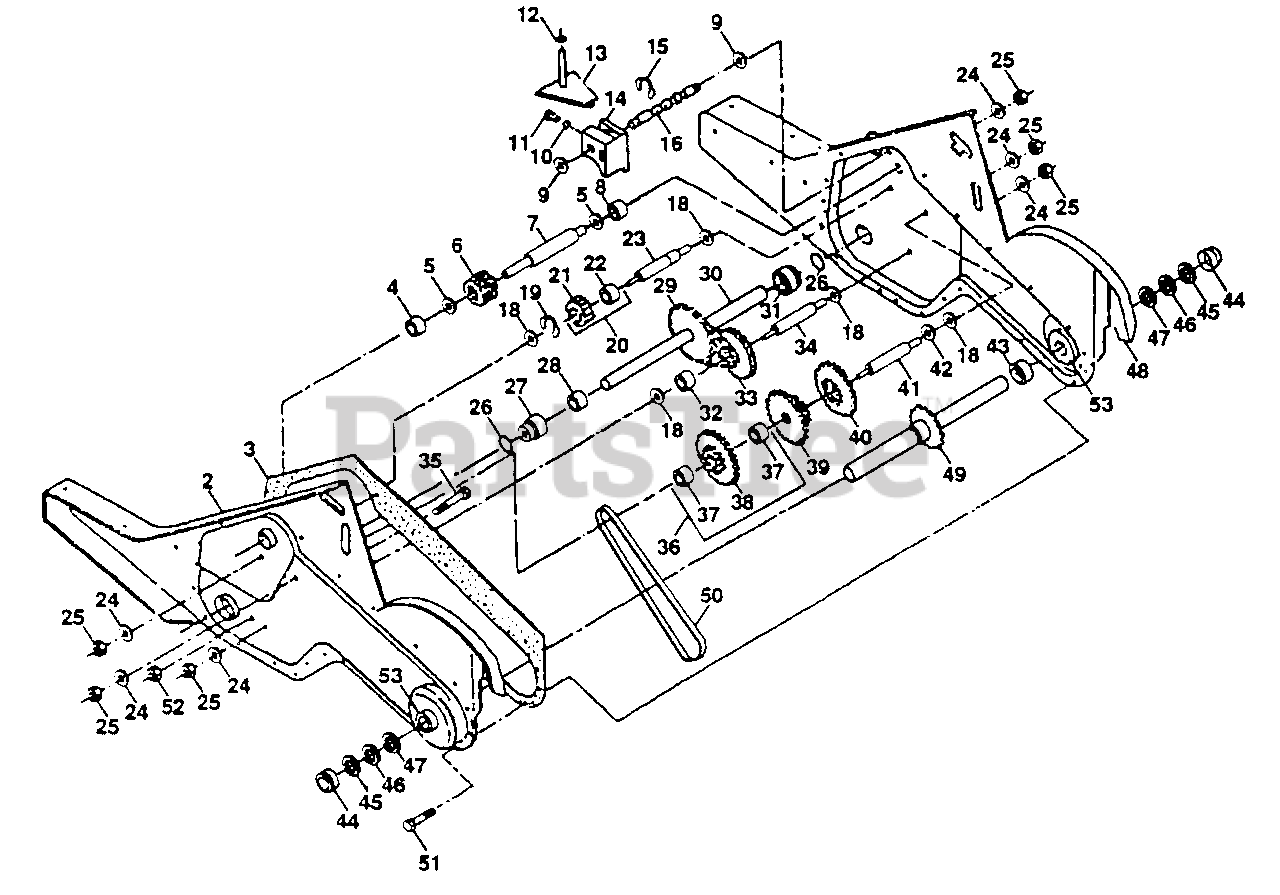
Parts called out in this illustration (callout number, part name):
1	Transmission Assembly (Includes Key Nos. 2-52) (AYP part number)
2	Gearcase, L.H. w/Bearing (Incl. 4) (AYP part number)
3	Gasket, Gearcase (AYP part number)
4	Bearing, Needle (AYP part number)
5	Washer, Thrust 5/8 x 1.10 x 1/32 (AYP part number)
6	Pinion, Input
7	Shaft, Input (AYP part number)
8	Bearing, Needle (AYP part number)
9	Washer, Seal (AYP part number)
10	Ball, Steel (AYP part number)
11	Spring, Shift, Fork (AYP part number)
12	O-Ring (AYP part number)
13	Arm, Shift
14	Fork, Shift
15	Ring, Klip (AYP part number)
16	Shaft, Shift (AYP part number)
18	Washer (AYP part number)
19	Ring, Klip (AYP part number)
20	Gear, Assembly, Reverse Idler (Includes Key Nos. 21 and 22)
21	Gear, Reverse Idler (AYP part number)
22	Bearing, Needle (AYP part number)
23	Shaft, Reverse Idler (AYP part number)
24	Washer, Lock 7/16 (AYP part number)
25	Nut, Hex 7/16-20 (AYP part number)
26	O-Ring (AYP part number)
27	Bearing, Shaft, Ground Drive (AYP part number)
28	Spacer 0.765 x 1.125 x 1.23 (AYP part number)
29	Chain #35-50 Pitch (AYP part number)
30	Ground Shaft Assembly
31	Bearing, Shaft, Ground Drive (AYP part number)
32	Spacer 0.70 x 1.00 x 1.150 (AYP part number)
33	Sprocket and Gear Assembly (AYP part number)
34	Shaft, Reduction (2nd) (AYP part number)
35	Screw, Whiz, Lock 5/16-18 x 3-1/2 (AYP part number)
36	Sprocket Assembly w/Bearing (Includes Key Nos. 37 and 38) (AYP part number)
37	Bearing, Needle (AYP part number)
38	Sprocket, Tine (AYP part number)
39	Gear, Cluster, Red 1st & 2nd (AYP part number)
40	Gear, Reverse (AYP part number)
41	Shaft, Reduction (1st) (AYP part number)
42	Washer, Thrust (AYP part number)
43	Spacer 1.01 x 1.75 x 0.760
44	Cup, Formed (AYP part number)
45	Ring, Spiral (AYP part number)
46	Seal, Ring, Rubber (AYP part number)
47	Seal, Oil (AYP part number)
48	Gearcase, R.H. w/Bearing (Includes Key No. 8) (AYP part number)
49	Shaft, Tine (AYP part number)
50	Chain, Roller #50-50 Pitch (AYP part number)
51	Screw 1/4-20 x 1/2 (AYP part number)
52	Nut, Hex 5/16-18 (AYP part number)
53	Kit, Bearing (AYP part number)
